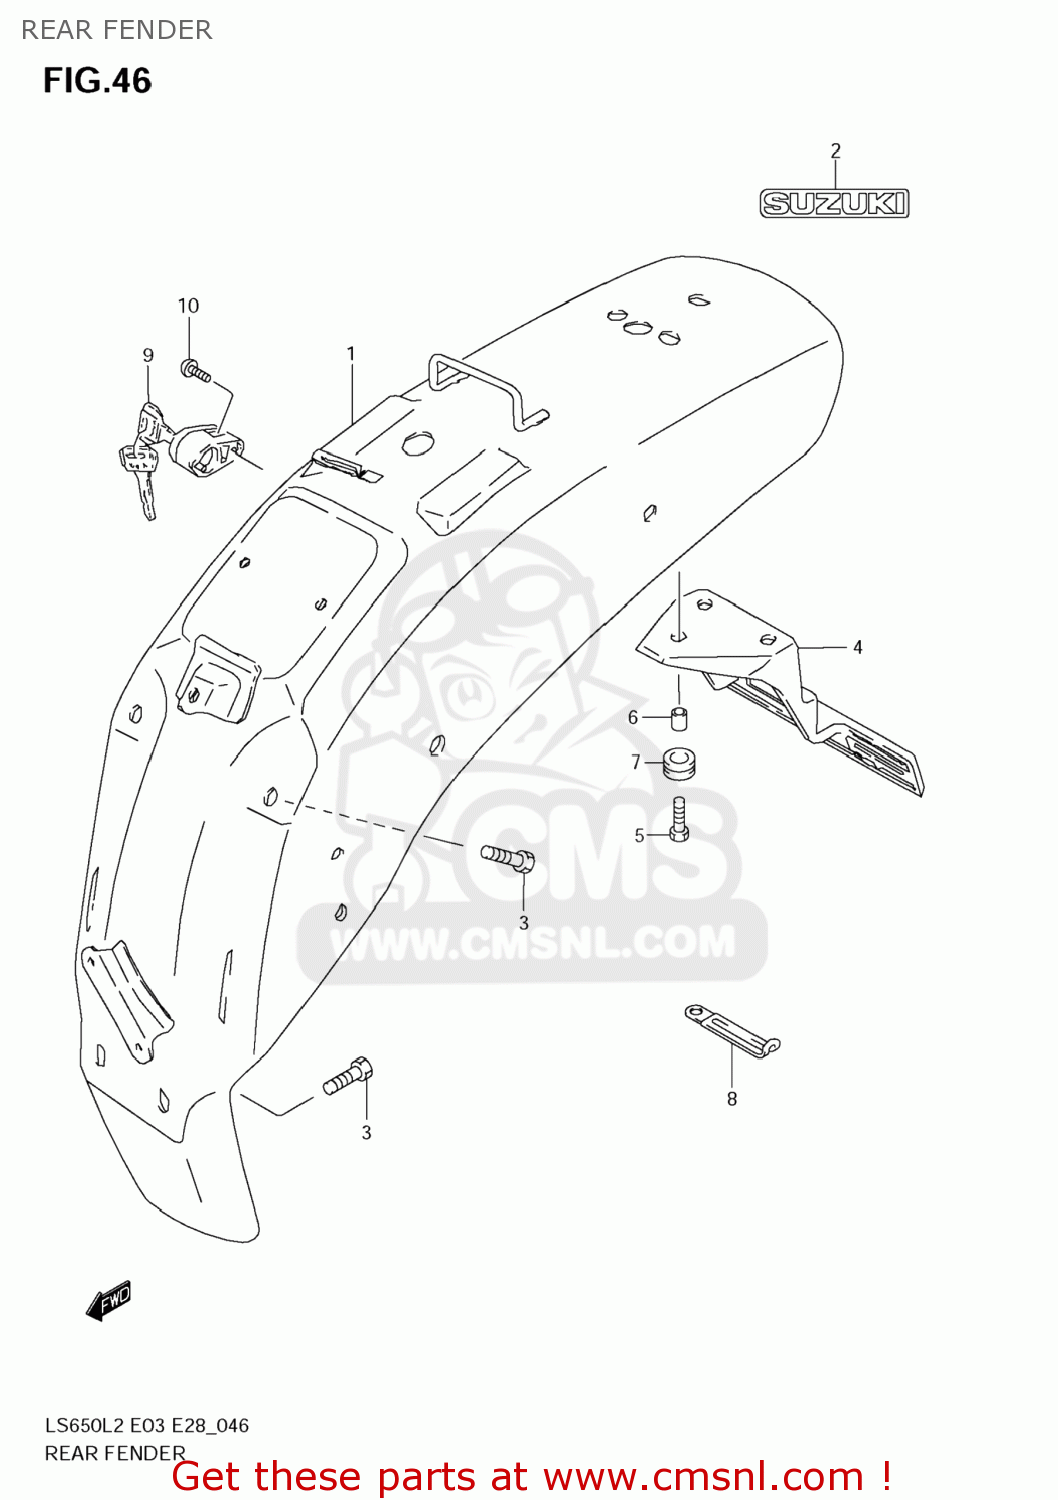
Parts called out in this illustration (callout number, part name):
1	FENDER ASSY,RR
2	EMBLEM,SUZUKI
3	BOLT(8X25)
4	BRACKET,LICENSE PLATE
5	BOLT(6X20)
6	SPACER(6.5X9X9)
7	CUSHION
8	CLAMP(L:45)
9	LOCK SET,HELMET
10	SCREW
